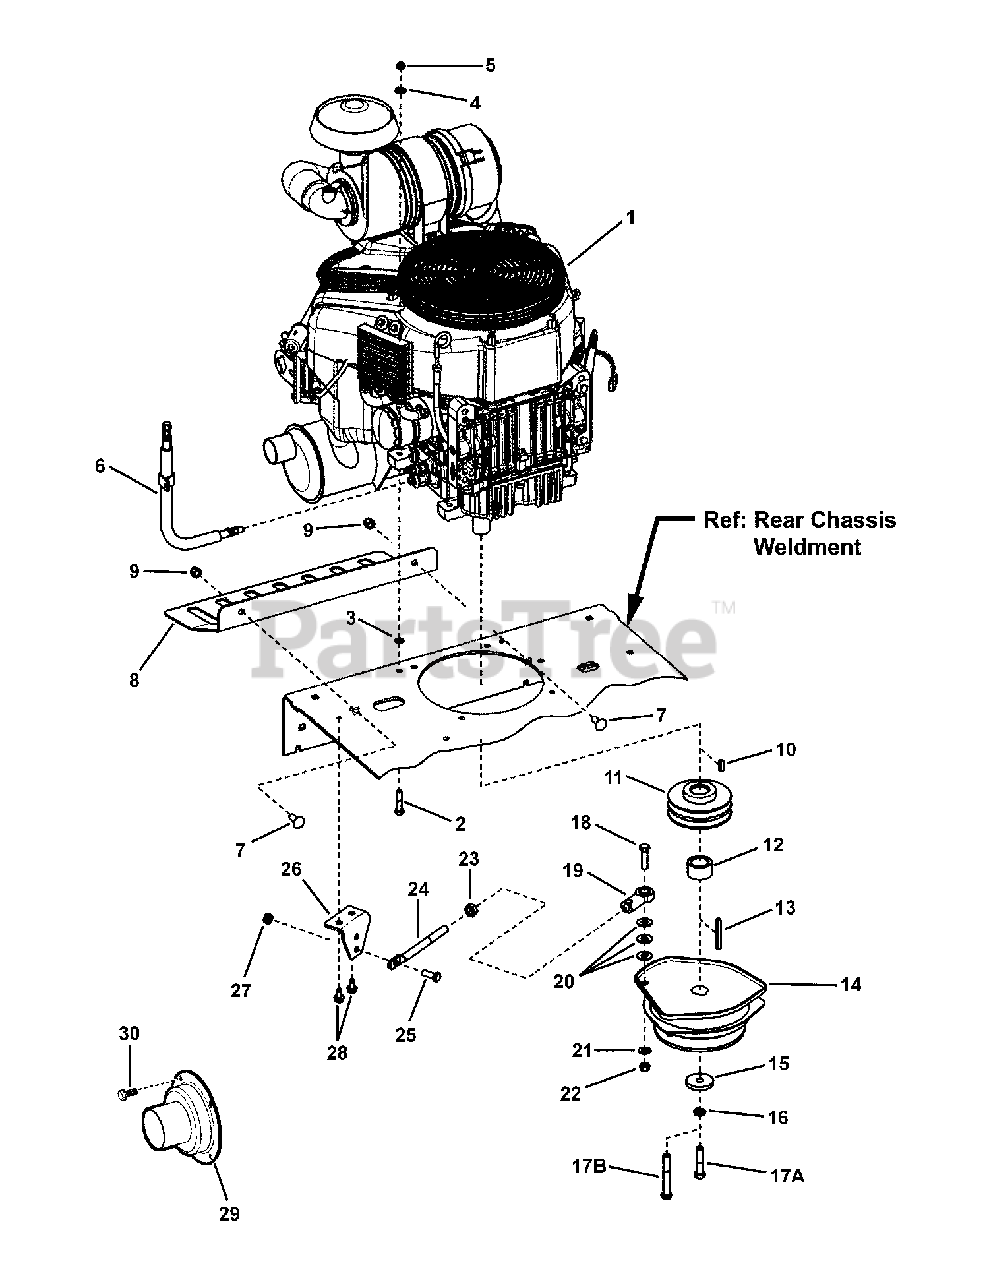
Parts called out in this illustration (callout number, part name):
1	* ENGINE, 32 HP Briggs Vanguard Vertical
2	SCREW, 5/16-18 x 1-1/2" Hex Head Cap, GR 5
3	BOLT RETAINER, 5/16" Bolt
4	WASHER, 5/16" Flat
5	NUT, 5/16-18 Hex Top Lock GR B
6	ASSEMBLY, Oil Drain Hose
7	BOLT, 3/8-16 x 1" Square Neck Carriage GR 5
8	GUARD, Muffler NZMX
9	NUT, 3/8-16 HEX NYLON LOCK
10	KEY, 1/4" Square x .360"
10	KEY, 1/4" Square x 3/4"
11	PULLEY, 4.26 O.D. x 1.375 OAL x 1.125 Bore
12	SPACER, Clutch
13	KEY, 1/4" Square x 2-1/4" Long
14	ELECTRIC CLUTCH, GT3.5
15	WASHER, .468 x 1.85 x .25 Flat
16	WASHER, 7/16" Split Lock
17A	SCREW, 7/16-20 x 2" Hex Head Cap, GR 5
17B	BOLT, 7/16-20 X 3" GD5
18	SCREW, 3/8-16 x 1-1/2" Hex Head Cap, GR 5
19	ROD END, Ball Joint 1/2-20 Female
20	WASHER, 3/8" USS
21	WASHER, 3/8" Flat SAE
22	NUT, 3/8-24 Hex, GR B
23	NUT, 1/2-20 Hex Jam, GR 5 or B
24	CLUTCH ROD (1/2-20 thread)
25	BOLT, 3/8-16 X 1" GD5 CZ
26	BRACKET, Clutch
27	NUT, 3/8-16 Hex Center Lock
28	SCREW, 5/16-18 x 5/8" Hex Washer Self-Tap
29	OUTLET, Muffler
30	SCREW, #8-18 x 1/2" Hex Washer Self-Tap
